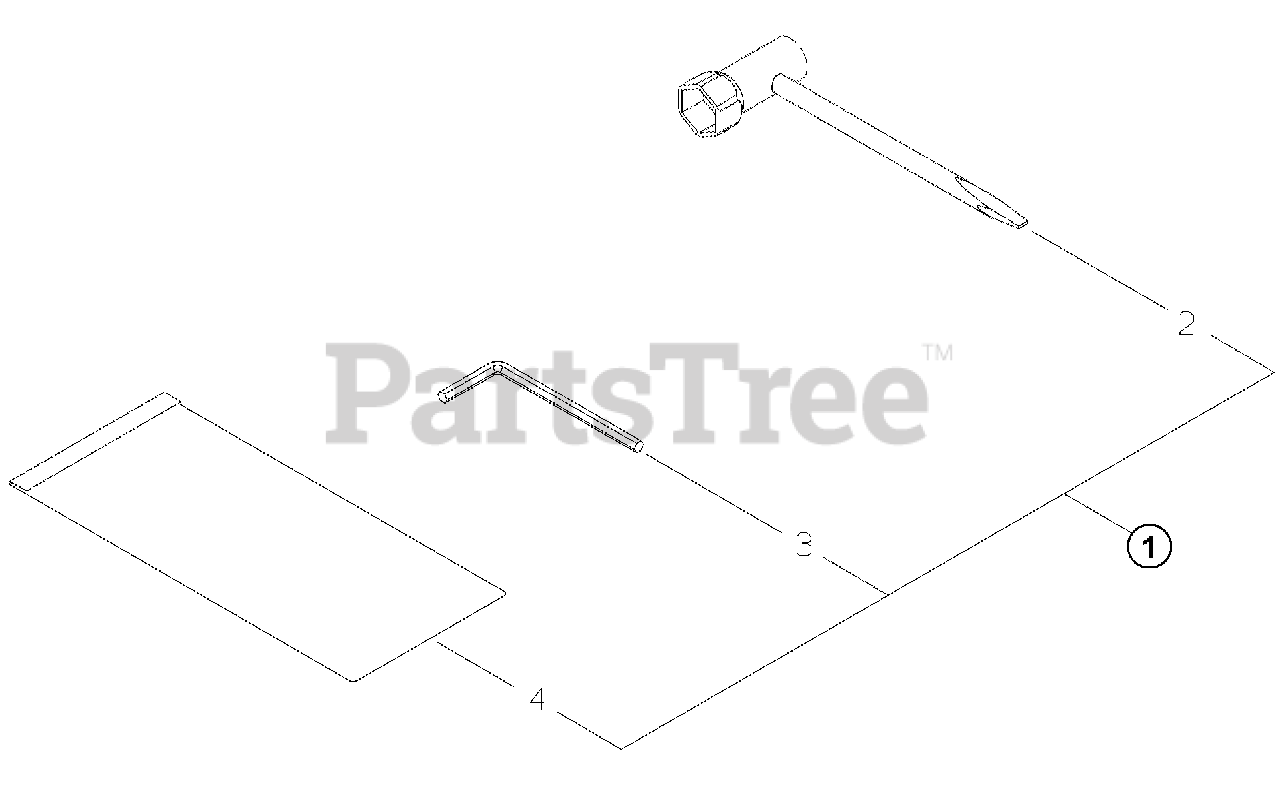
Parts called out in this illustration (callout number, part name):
1	TOOL KIT
2	T-WRENCH - 13X16mm
3	HEX KEY - 4mm
4	BAG, TOOL
